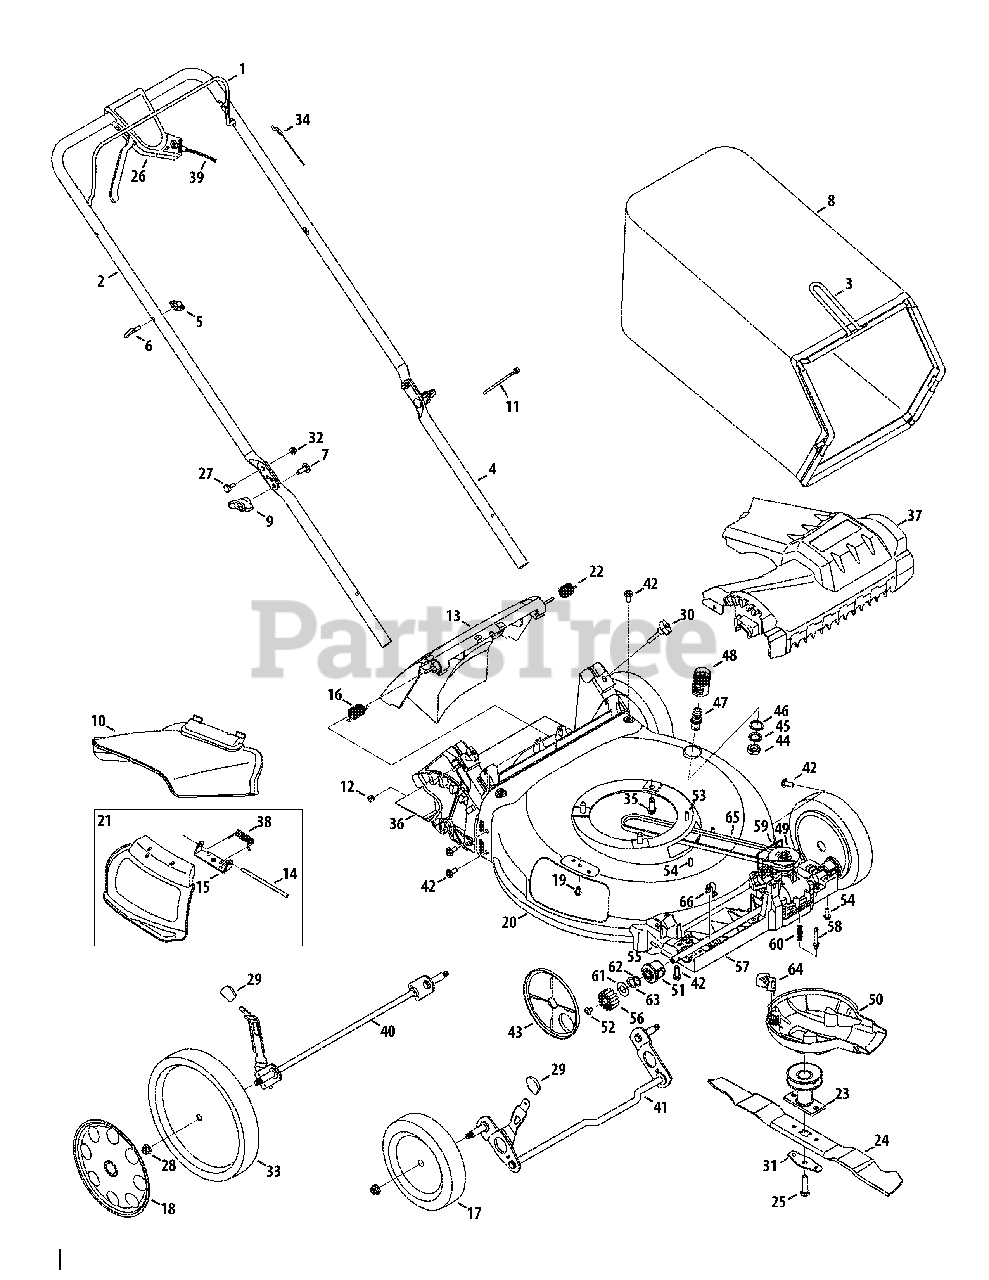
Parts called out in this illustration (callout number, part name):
1	Blade Control
2	Upper Handle
3	Grass Catcher Frame
4	Lower Handle
6	Rope Guide
7	Carriage Screw, 5/16-18
8	Grass Bag
10	Side Chute
11	Cable Tie
12	Nut, Sq., 1/4-20
13	Rear Discharge Door & Baffle Assembly-Generic
13	Rear Discharge Door & Baffle Assembly-Lowes
14	Hinge Pin
15	Chute Deflector Bracket
16	Torsion Spring - RH
17	Front Wheel
19	Screw, 1/4-20 x .500
20	Deck , 21"
21	Hinged Mulch Plug Assembly
22	Torsion Spring - LH
23	Blade Adapter Assembly
24	Mulching Blade
25	Screw , 3/8-24 x 1.50
26	Control Lever Assembly
27	Sldr. Screw, .375 x .126 x 1/4-20
28	Flange Lock Nut, 3/8-16
29	Adjustment Lever Knob
30	Wing Nut
31	Blade Bell Support
32	Nut, Flange Lock, 1/4-20
33	Rear Wheel
34	Control Cable
35	TT Sems Screw, 3/8-16 x 1.0
36	Trail Shield
37	Front Cover
38	Torsion Spring
39	Variable Speed Cable
40	Rear Axle Assembly
41	Front Axle Assembly
42	Screw, 5/16-14 x .750
43	Wheel Dust Cover
44	Nut, Hex
45	Washer, Lock, 5/8"
46	Wash., Flat, .865 x 1.145 x .030
47	Water Nozzle
48	Water Nozzle Adapter
49	Transmission Assembly
50	Engine Baffle
51	Bearing Assembly
52	Screw, 1/4-20 x .390
53	Screw, 1/4-20 x .500
54	Screw, 1/4-15 x .750
55	Dowel Pin
56	Spur Gear, 14T - RH
56	Spur Gear, 14T - LH
58	Spring Body
59	Transmission Wire
60	Compression Spring
61	Wash., Flat, .508 x 1.00 x .020
62	Wash., Flat, .504 x .700 x .010
63	Wash., Saddle, .505 x .740 x .125
64	Engine Baffle Bracket
66	Front Axle Clip
